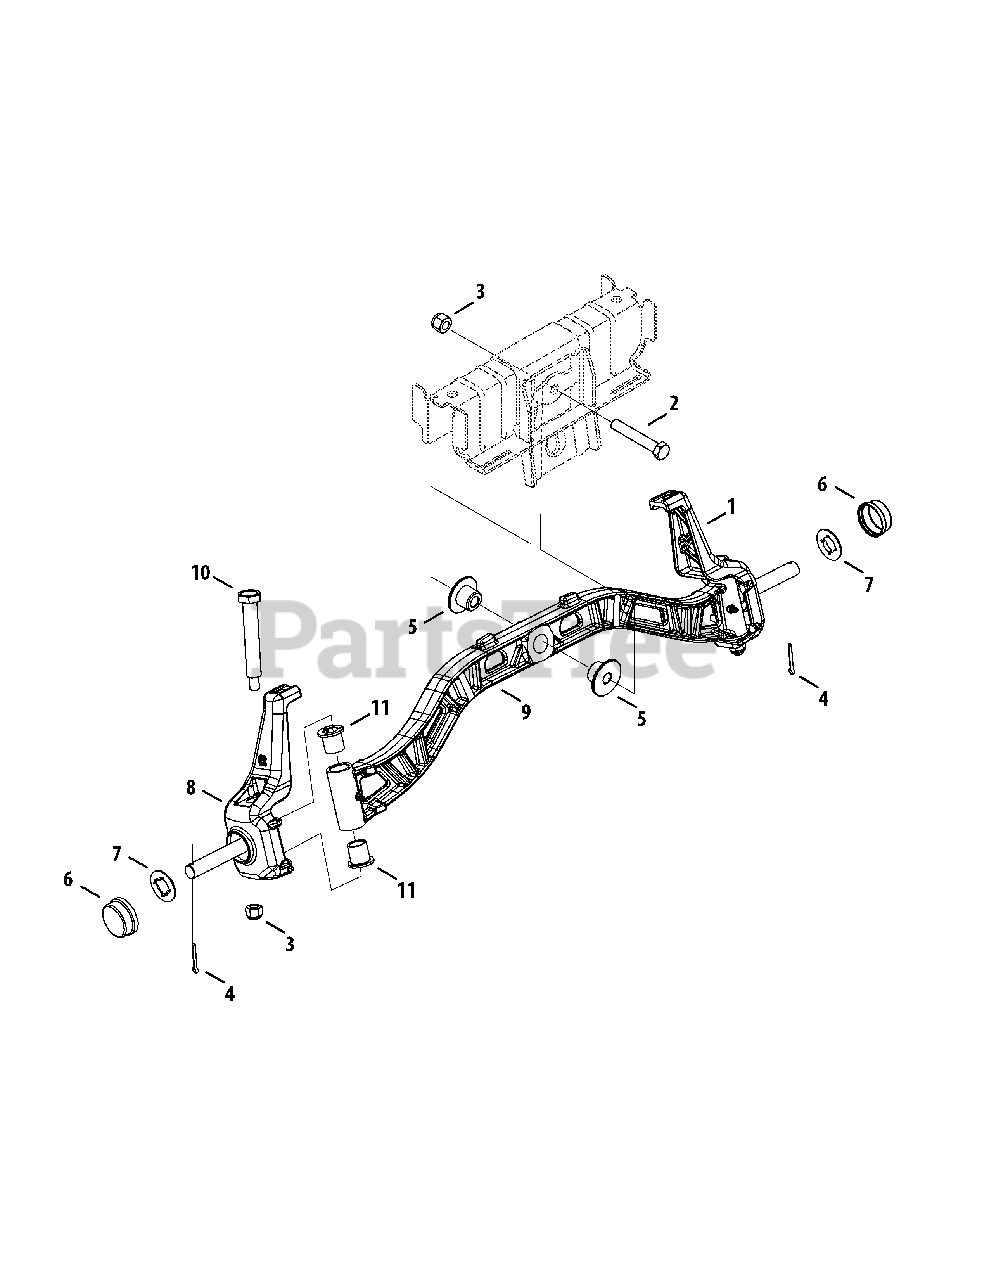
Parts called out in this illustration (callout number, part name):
1	Steering Axle Assembly, LH
2	Hex Cap Screw, 1/2-13 x 3.00
3	Nut, Hex Lock, 1/2-13
4	Pin, Cotter, 5/32, 1.25
5	Shoulder Spacer, 1.00 x .515 x .760
6	Hub Cap
7	Washer, Flat, .350 x 1.559 x .062
8	Steering Axle Assembly, RH
9	Pivot Axle, Cast
10	Shoulder Bolt, .75 x 4.20, 1/2-13
11	Flange Bearing, .75 x 1.00 x 1.12
